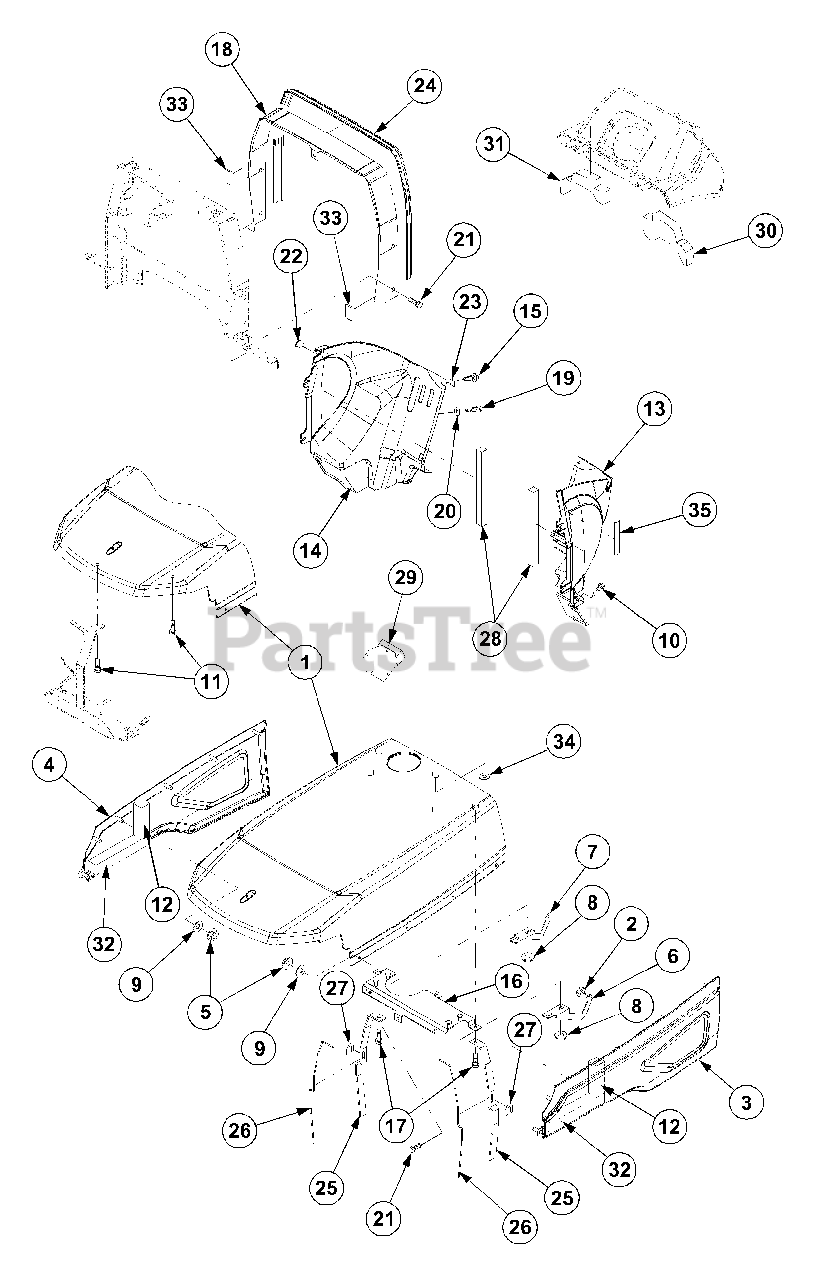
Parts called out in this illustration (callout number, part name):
3	Cover,Side L.H
4	Cover,Side R.H
6	Plate L.H
7	Plate R.H
11	Bolt,w/Washer
13	Panel,Rear L.H
14	Panel,Rear R.H
15	Bolt,w/Washer
16	Plate
17	Bolt,w/Washer
21	Bolt,w/Washer
22	Plug
24	Weather Strip
25	Plate
27	Liner
